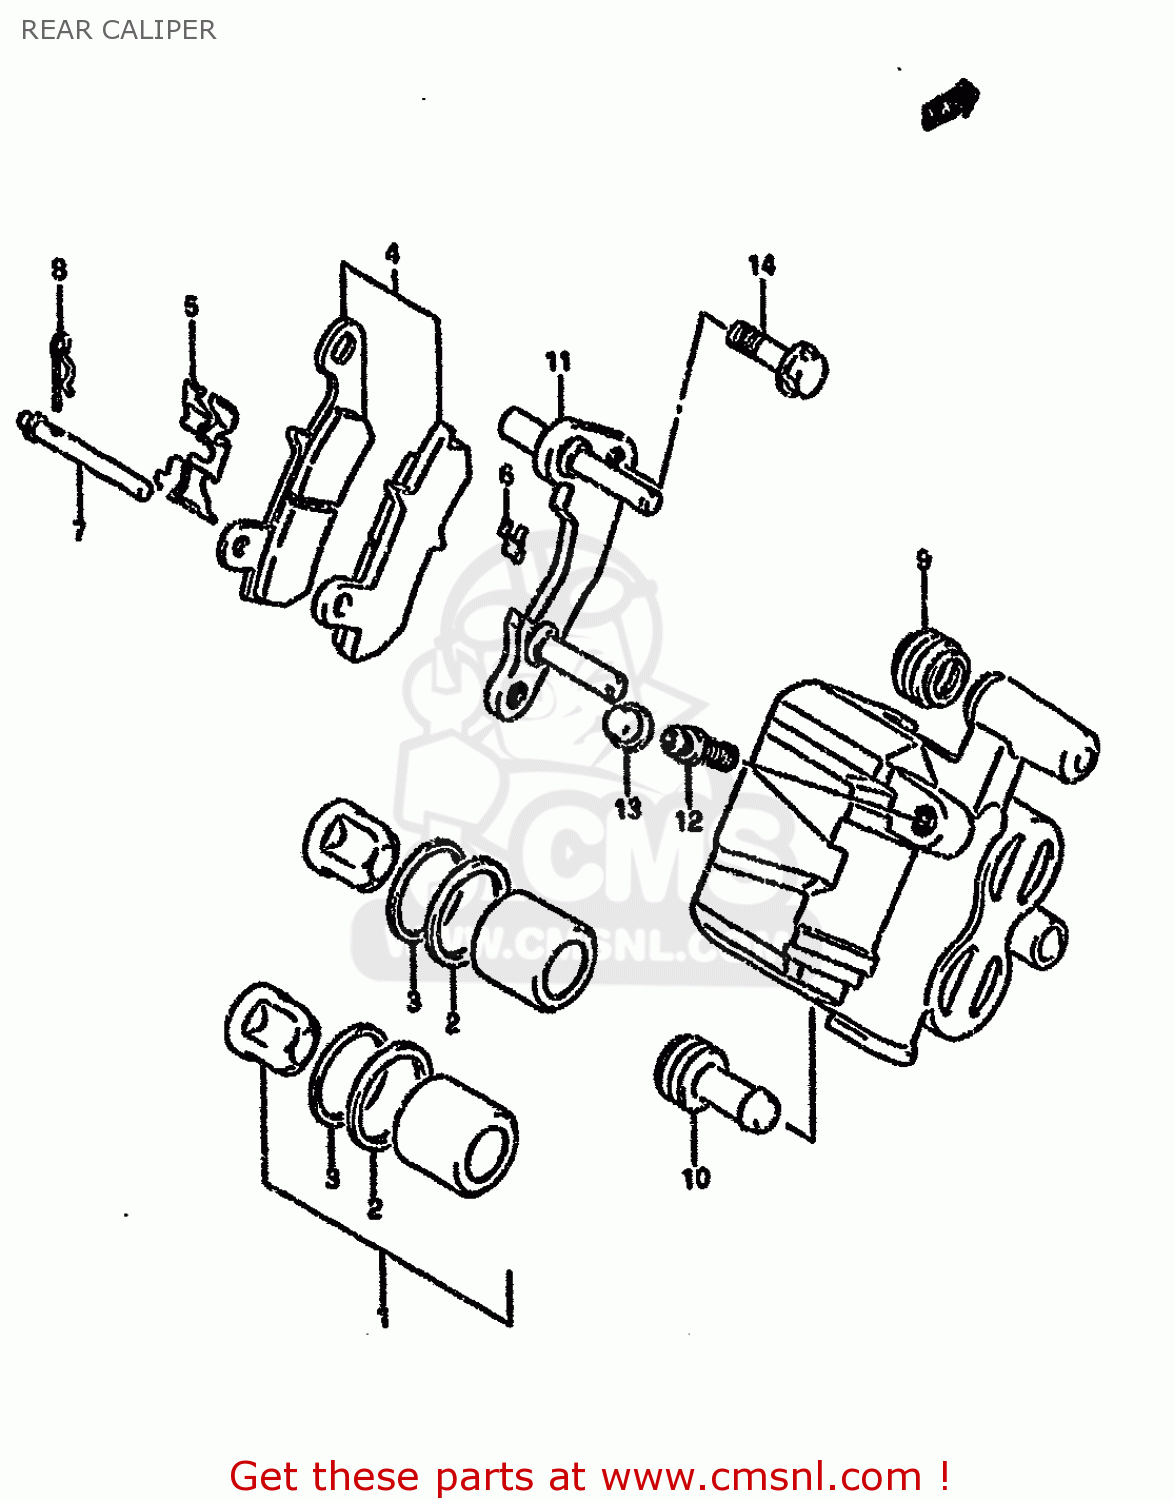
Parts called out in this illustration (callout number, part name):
1	BRAKE PISTON SET
2	SEAL,PISTON
3	SEAL,WIPER
4	PAD SET (NAS)
5	SPRING,PAD
6	GUIDE,PAD
7	PIN,PAD
8	CLIP,PAD PIN
9	BOOT,AXLE
10	INSULATOR,AXLE
11	CARRIER
12	BLEEDER
13	CAP,BLEEDER PLUG
14	BOLT(8X22)
